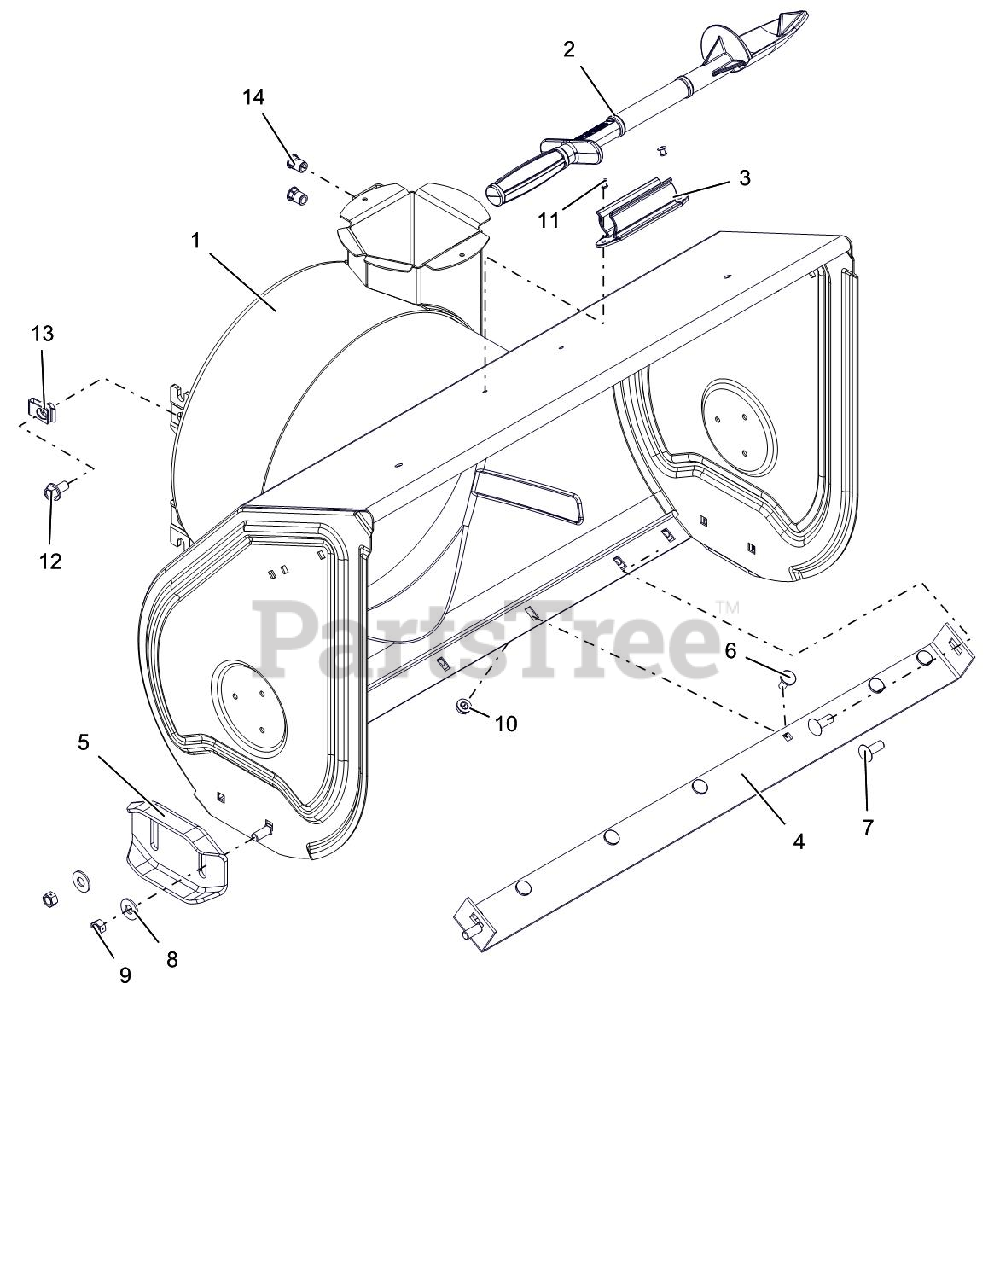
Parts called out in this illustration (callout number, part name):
1	BLOWER HOUSING W/DECAL 30"
2	DEVICE, SNOW CLEAN OUT
3	MOUNT, SNOW CLEAN OUT
4	BLADE, SCRAPER-30"
5	SKID SHOE, REVERSIBLE - ORANGE
6	BOLT, MODIFIED HEAD CARRIAGE
7	@BLT-RDHDSHSQNK.38-16X1.0 G5YZ
8	@WSHR-FL-STL.438X1.00X.083 YWZ
9	@NUT-LK-CTR .38-16 YWZC
10	@NUT-LK-TOP-FLG .31-18 YWZC
11	RVT-POP .187 YZ
12	BLT-SERHFWH .38-16X.75 YWZC
13	NUT-RTNR .375-16X.37
14	NUT, THREADED INSERT .38-16
